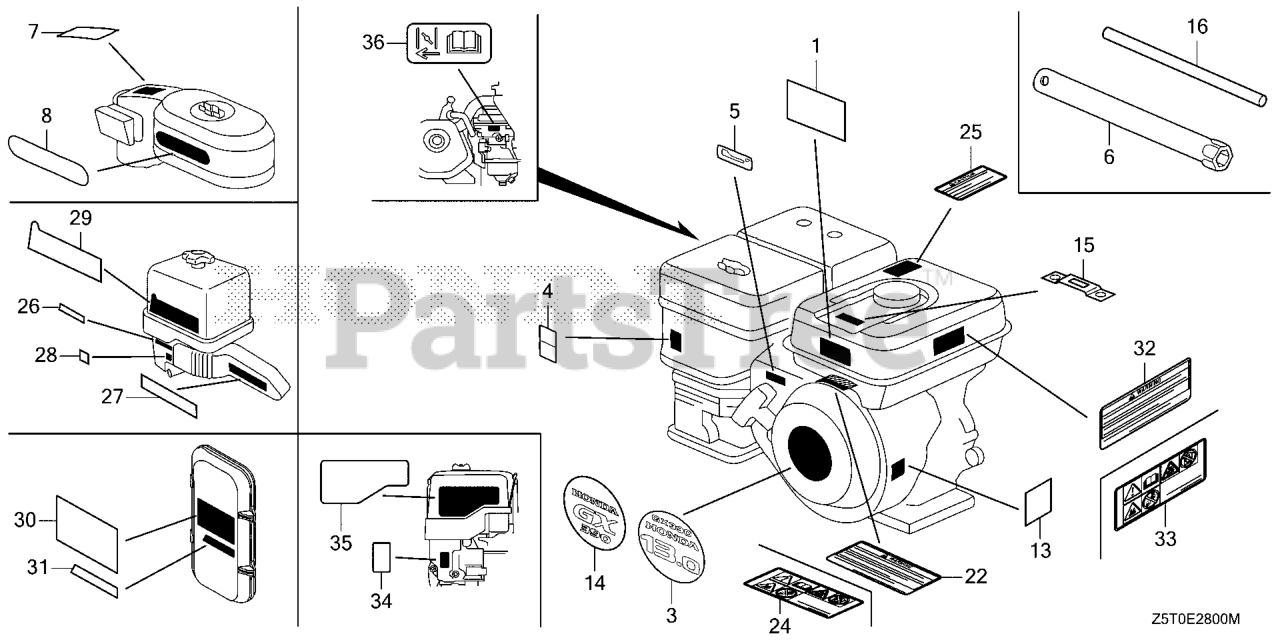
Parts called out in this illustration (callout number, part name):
6	WRENCH, SPARK PLUG
25	MARK, EX. CAUTION (ENGLISH)
26	MARK, CHOKE
27	MARK (HONDA)
28	MARK, FUEL
29	MARK, SALES POINT
32	MARK, OPERATOR CAUTION (ENGLISH)(MADE IN THAI)
36	MARK, CHOKE
